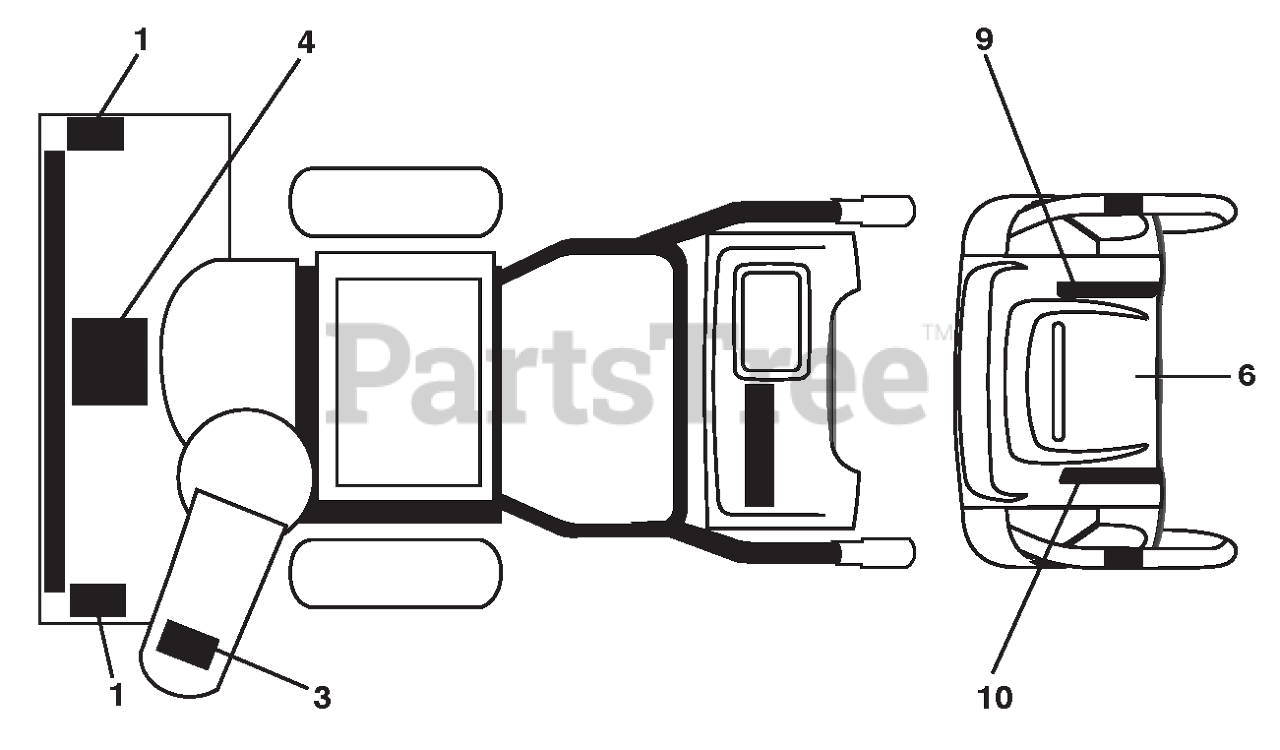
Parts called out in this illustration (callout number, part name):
1	DECAL.SNOWTHR.AUGER
3	DECAL.SNOWTHR.CHUTE.SAFETY
4	DECAL.SNOWTR.READ.OWN.MAN.E/F
6	DECAL.CONSOLE.SNOW.INST.ENG/FR
9	DECAL.CONS.RH.INST.GRY
10	DECAL.CONS.LH.REMOTE.INST.GRY
